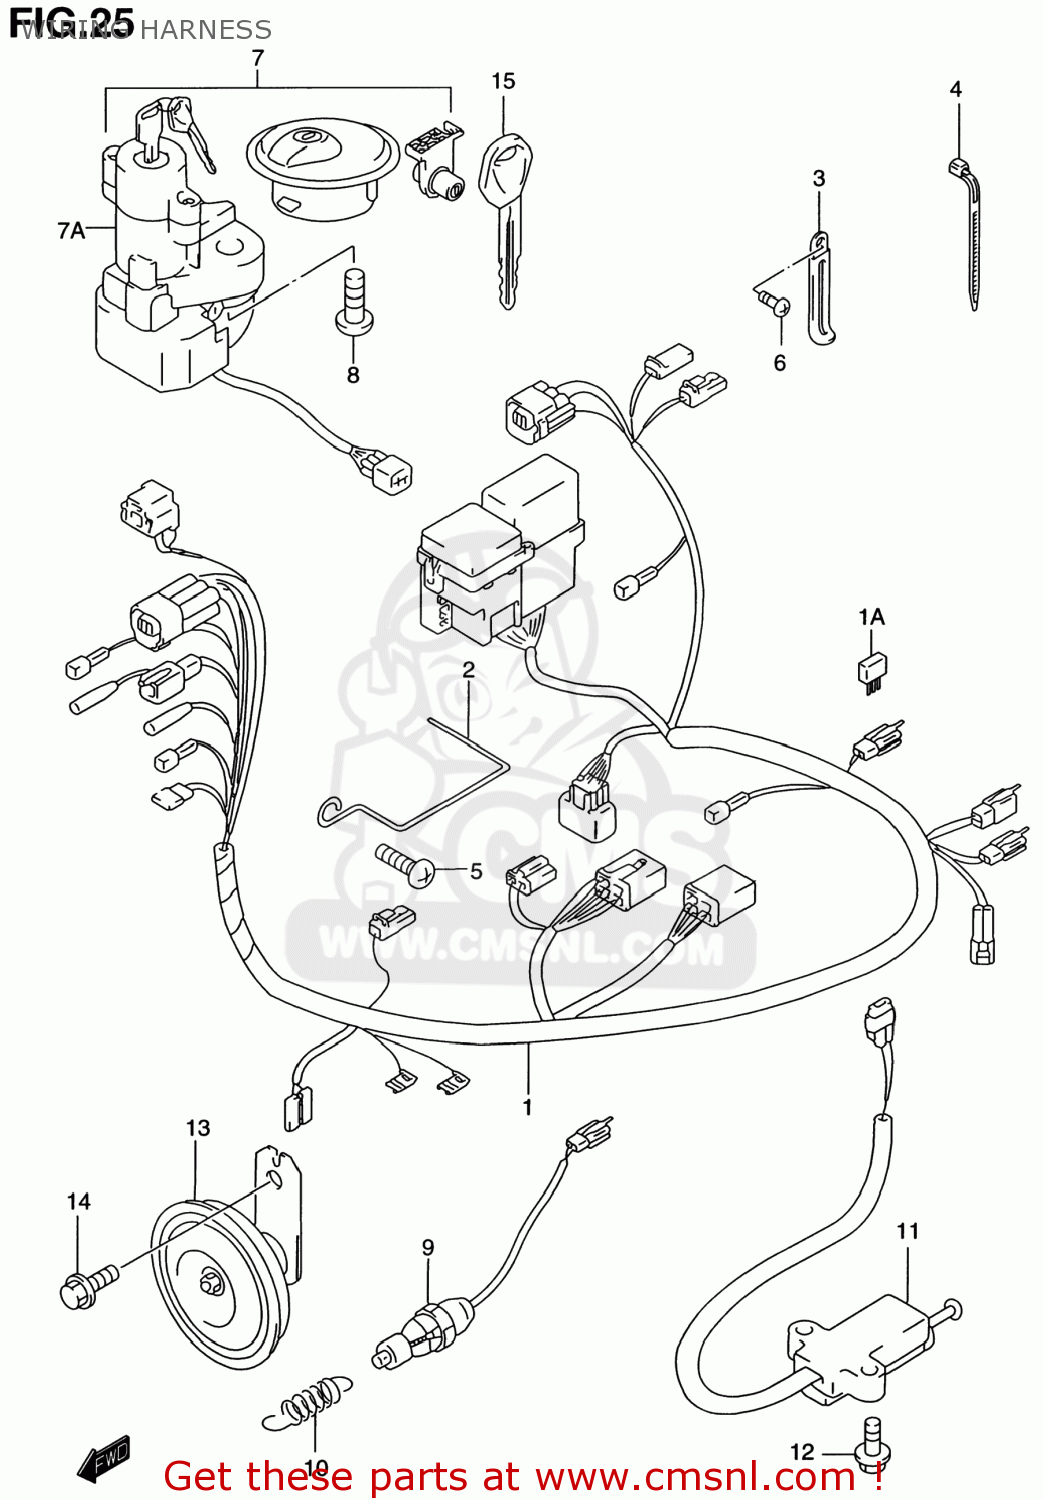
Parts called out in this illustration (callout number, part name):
1	HARNESS,WIRING
2	GUIDE,HARNESS
3	CLAMP(L:65)
4	CLAMP(L:125)
5	BOLT
6	SCREW
7	LOCK SET
7A	LOCK ASSY,STEERING
8	BOLT(8X20)
9	SWITCH ASSY,STOP LAMP
10	SPRING
11	SWITCH ASSY,SIDE STAND
12	BOLT
13	HORN ASSY
14	BOLT
15	KEY,BLANK
